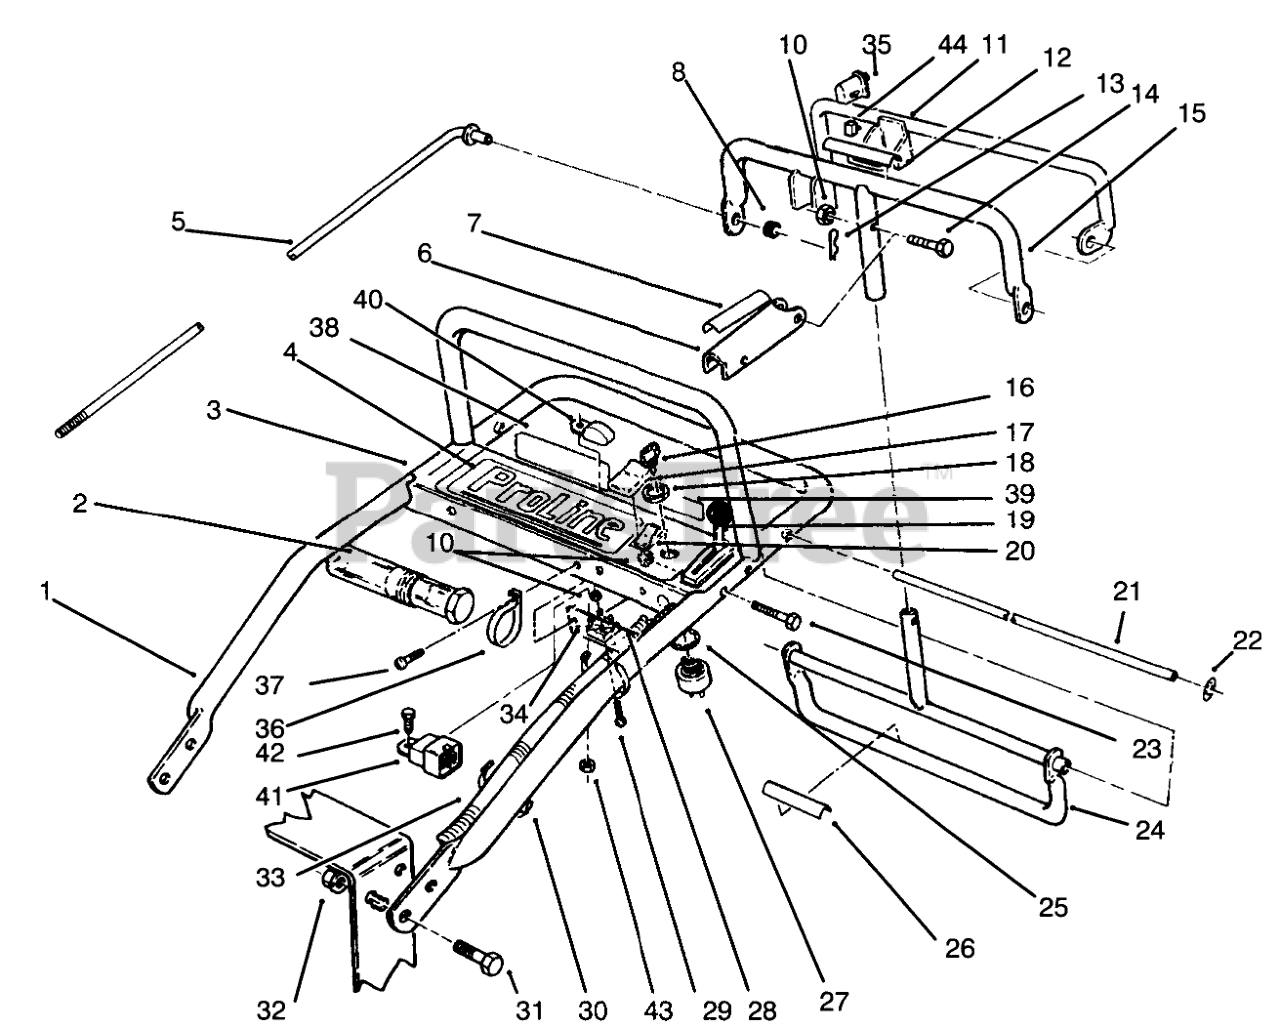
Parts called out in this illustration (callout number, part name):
1	Handle-Upper
2	TUBE-MANUAL
3	Panel-Control
4	DECAL-CONTROL PANEL
5	ROD-CONTROL
6	Lever-Parking Brake
7	DECAL-LEVER, PARKING
8	GROMMET-RUBBER
10	NUT-LOCK, NI
11	Bail
12	DECAL
13	PIN-COTTER
14	SCREW-SHH
15	Bar-Control
16	KEY-IGNITION
17	BOOT-SWITCH
18	NUT-HH
19	CONTROL-THROTTLE
20	SWITCH
21	PIVOT ROD
22	NUT-PUSH-ON, CIRCULAR
23	SCREW-SHH
24	Control Pivot
25	WASHER-TOOTH, INTERNAL
26	DECAL
27	Switch-Off/On (Incl. Ref. #16 18, & 25)
28	Panel-Bottom
29	SCREW-HWH
30	TIE-CABLE
31	SCREW-HHF
32	NUT-HF
33	Wire Harness (Ref.)
34	RECTIFIER-BRIDGE
35	SWITCH-BAIL
36	CLAMP-R
37	SCREW-SHWH
38	DECAL-INSTRUCTION
39	DECAL-INSTRUCTION, SAFETY
40	Module
41	RELAY
42	SCREW-HH
43	NUT-LOCK, NI
44	CONNECTOR-BODY
